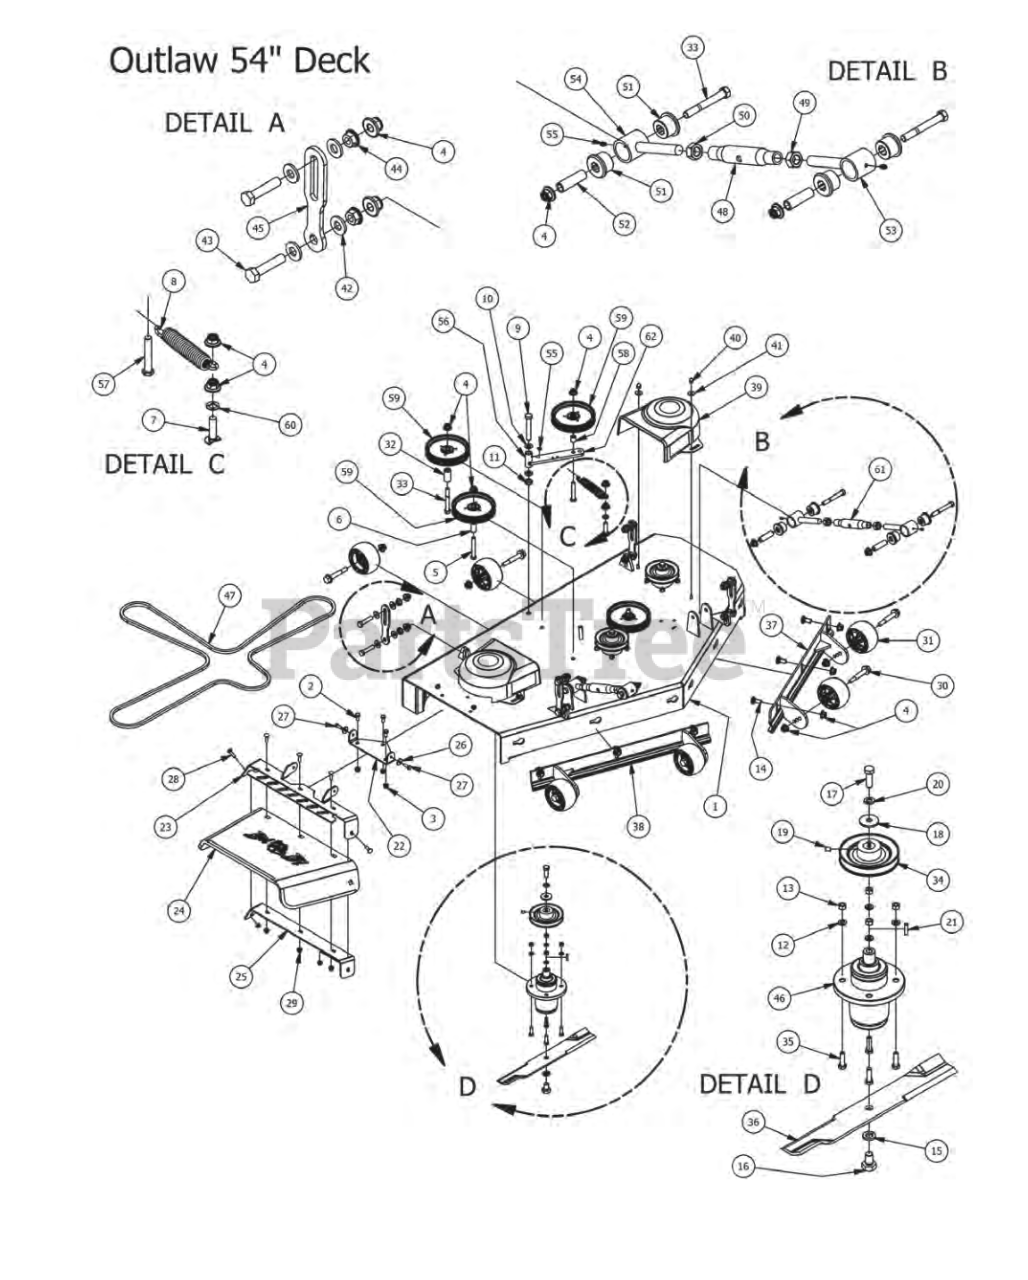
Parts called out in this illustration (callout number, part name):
1	2015 54" Deck
2	3/8" x 3/4" Hex Bolt
3	3/8" Flange Nut
4	1/2-13 Nylon Flange Nut-Orange
5	1/2 x 3 1/2 Flange Bolt Grade 8
6	502 ID X.75 OD X 1.500 Leng
7	1/2 x 2" Carriage Bolt
8	2015 Deck Idler Spring Outlaws
9	5/8" x 4" Hex Bolt
10	635 ID Plastic Washer
11	5/8-11 Nylon Insert Jam Half Nut
12	3/8 Lockwasher Zinc
13	3/8-16 Hex Nuts Zinc
14	1/2" x 1 1/4 Carriage Bolt
15	5/8" Lock Washer
16	5/8" x 1 1/2" Gr& Hex Bolt (Fine)
17	1/2"-20 x 1 1/2 - Grade 5 Fine Thread Bolt
18	1/2 Belleville Washer
19	5/16 Set Screw
20	1/2" Lock Washer
21	1/4" x 1" Key
22	Discharge Chute Hanger (deck mounted)
23	60" Discharge Chute Upper Hanger
24	Rubber Discharge Chute
25	60" Discharge Lower Bracket
26	360 ID Plastic Washer
27	5/16" x 1" Bolt
28	5/16" x 1 1/4" Carriage Bolt
29	5/16" Flange Nut Zinc W/Serrations
30	Deck Wheel Bolt
31	Anti-Scalp Rollers
32	1 3/4" Pulley Spacer
33	1/2" x 4" Bolt (Grade 8)
34	5 Deck Pulley
35	3/8" x 1 1/4" Hex Bolt
36	54" Deck Fusion Blade For Outlaw
37	54 Deck Adustable Front (Left)
38	54 Deck Adustable Front (Right)
39	Pulley Cover
40	Acom nut-pulley Cover
41	360 ID Plastic Washer-Black
42	505 Nylon Spacer
43	1/2-13X 2-1/4 GR Hex Bolts
44	1/2" Flange Nut
45	Deck Hanging Tab
46	OUTLAW SPINDLE ASSEMBLY
47	60 ZT Deck Belt
49	3/4-10 Left-Handed Hex Nuts Zinc
50	3/4-10 Hex Nuts Zinc
53	Turn Left-Handed
54	Right-Handed End
55	1/4" Press in Grease Fitting
56	Deck Idler
57	1/2-13 x GR 5 Hex Bolt Zinc
58	3/4 OD x 1/2 ID x 3\4 Length
59	5-3/4 Idler Pulley
60	517 Square Hole Round Washer
61	Turnbuckle Assembly
62	Deck Idler Assembly -Includes parts: 4,10,59,60,61
